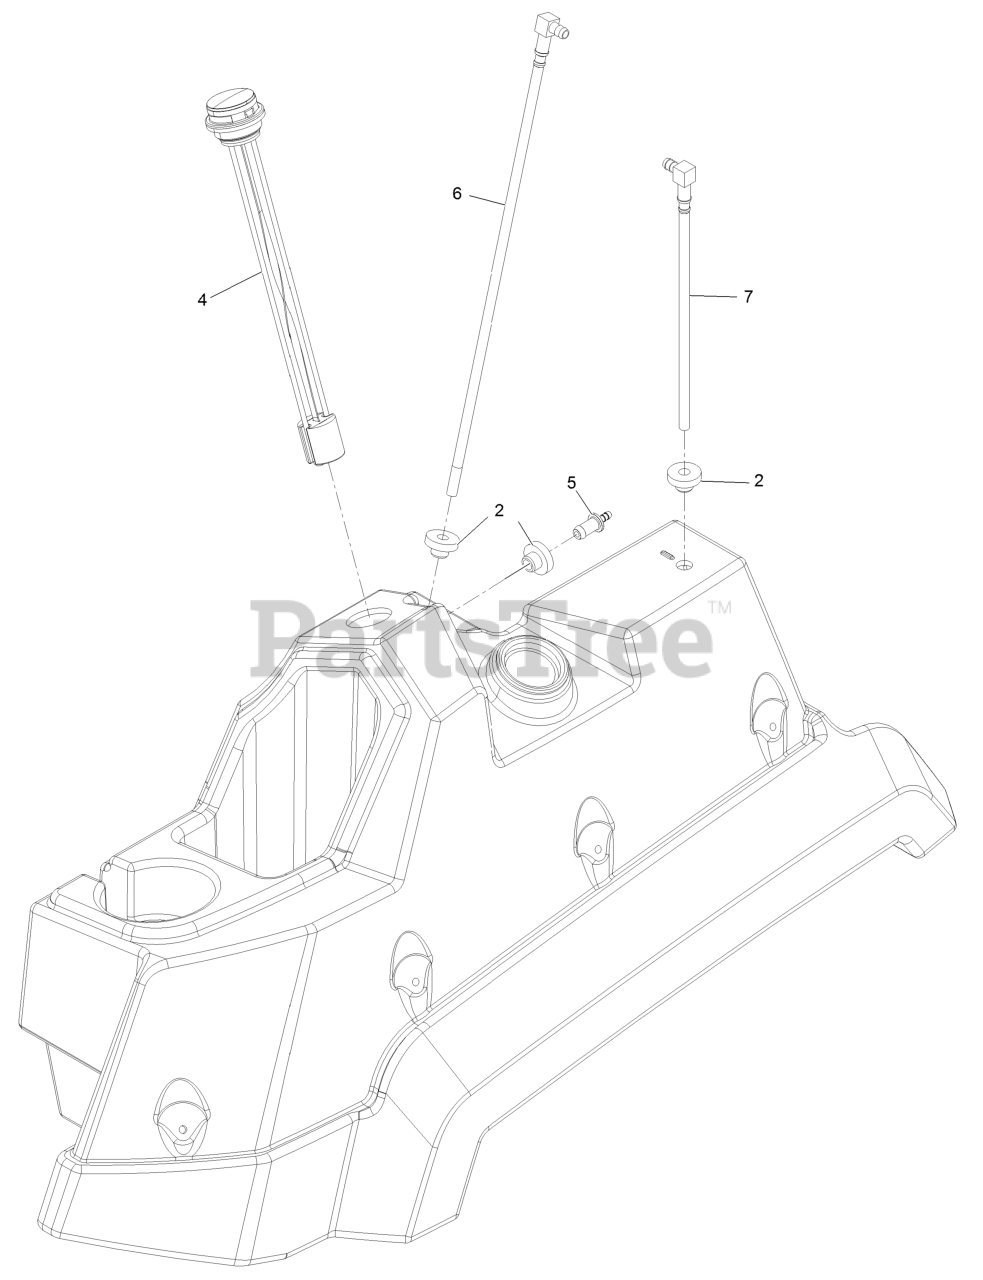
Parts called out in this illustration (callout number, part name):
2	Bushing
4	Gauge-Fuel
5	Fitting-Orifice, Straight
6	Pick-Up-Fuel
7	Return-Fuel
